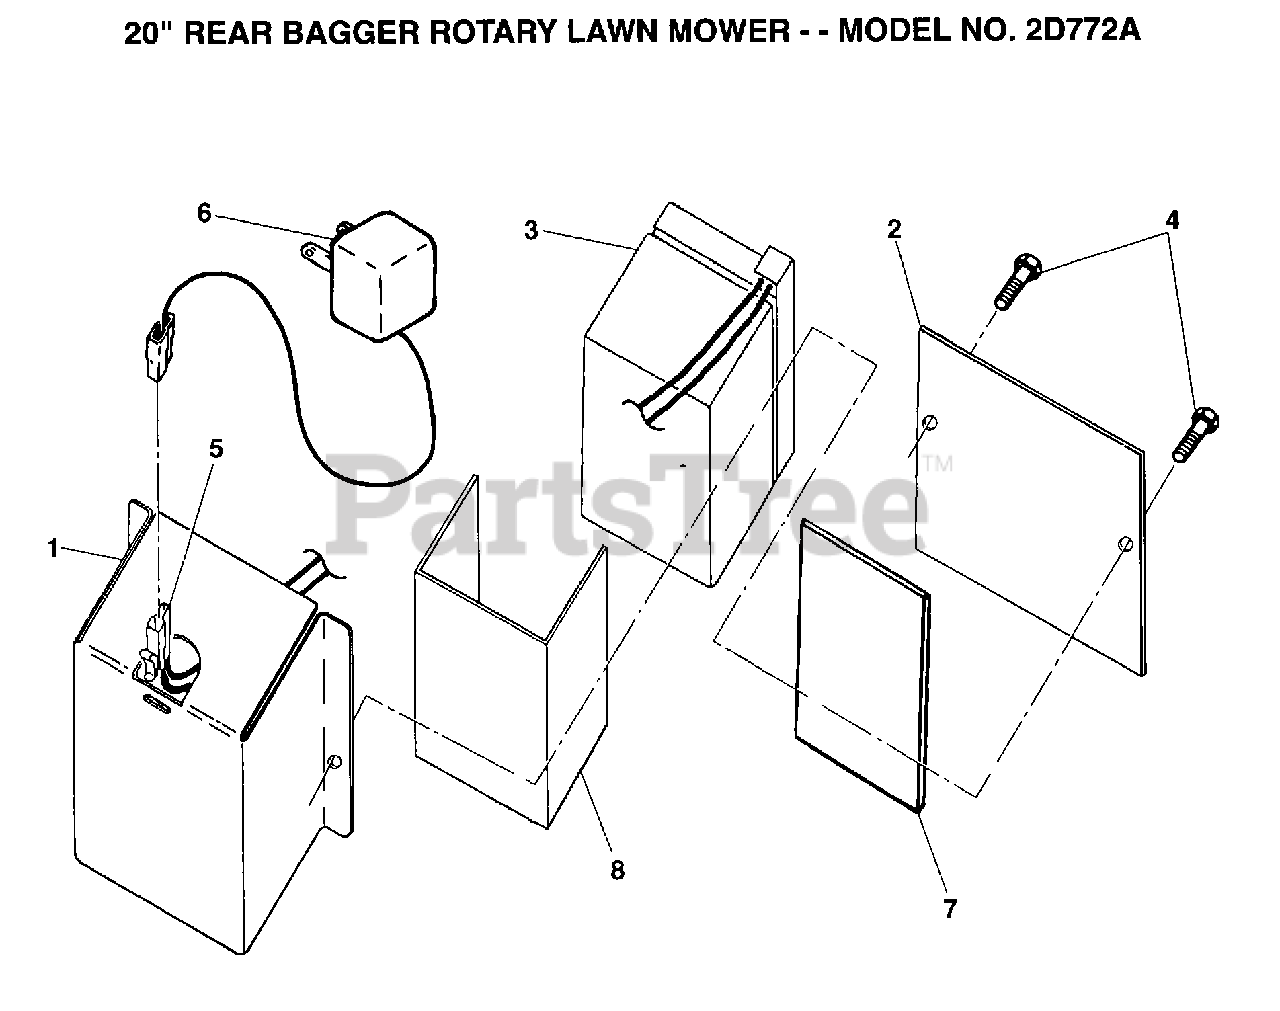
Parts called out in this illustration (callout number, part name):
4	SCREW SELF TAP
5	CONNECTOR PM
6	CHARGER PM
7	"PAD PM, BATTERY"
8	"WRAP, BATTERY"
